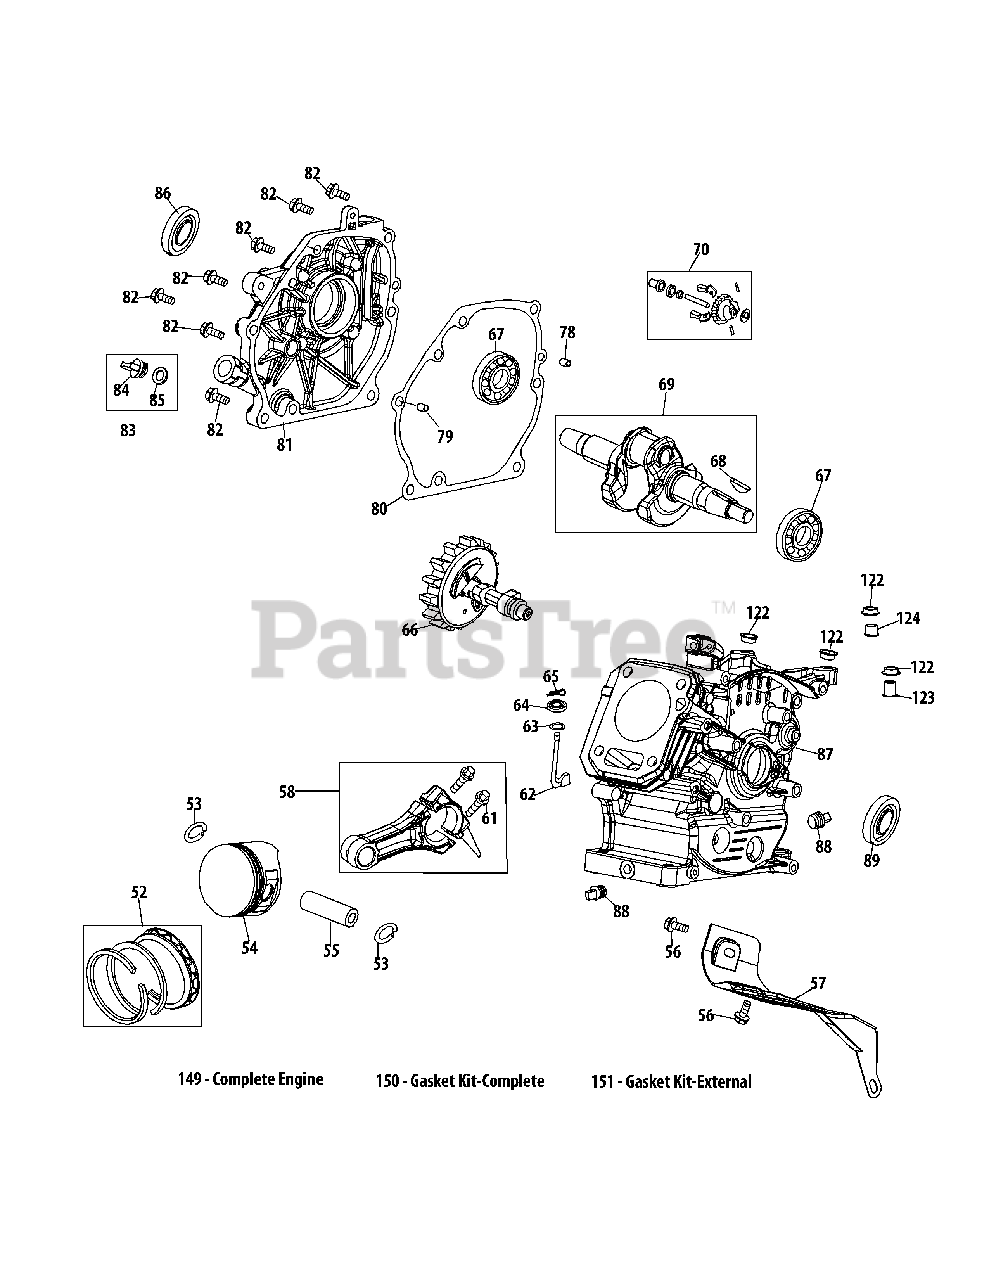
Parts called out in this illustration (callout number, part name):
52	Piston Ring Set
53	Piston Pin Snap Ring
55	Piston Pin
56	Bolt M6×12
57	Air Shield
58	Connecting Rod Assembly
61	Connecting Rod Bolt
62	Governor Arm
63	Washer 5.2×1.9
64	Governor Seal
65	Cotter Pin
66	Camshaft Assembly
67	Radial Ball Bearing, 6205
68	Woodruff Key
69	Crankshaft Assembly
69	Crankshaft Kit
70	Governor Gear/Shaft Assembly
78	Dowel Pin 7×14
79	Dowel Pin 9×14
80	Crankcase Cover Gasket
81	Crankcase Cover
81	Crankcase Cover Kit
82	Bolt M8×32
83	Oil Fill Plug Assembly
85	O-Ring 15.8×2.5
86	Oil Seal, 25×41.25×6
87	Crankcase Kit
87	Short Block Assembly
88	Oil Drain Plug
89	Oil Seal 25×41.25×6
122	Damping Rubber Pad
149	Complete Engine
150	Gasket Kit-Complete
151	Gasket Kit-External
